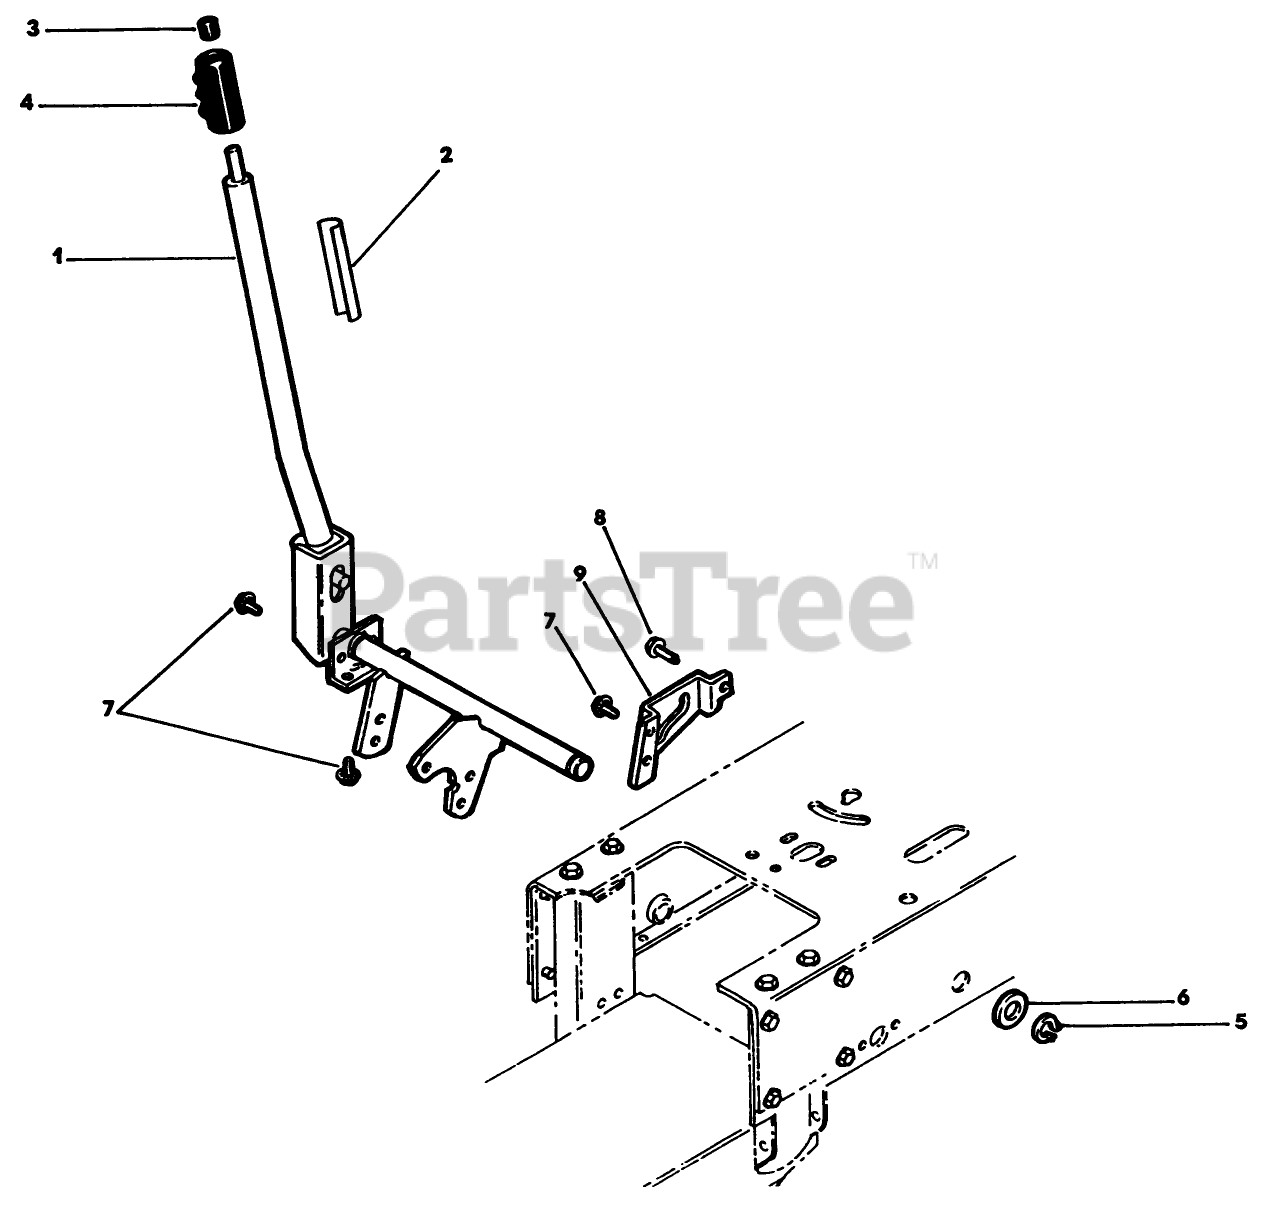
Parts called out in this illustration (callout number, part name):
2	STICKER-LIFT
3	TIP-ROD
5	RING-RETAINING
6	WASHER
